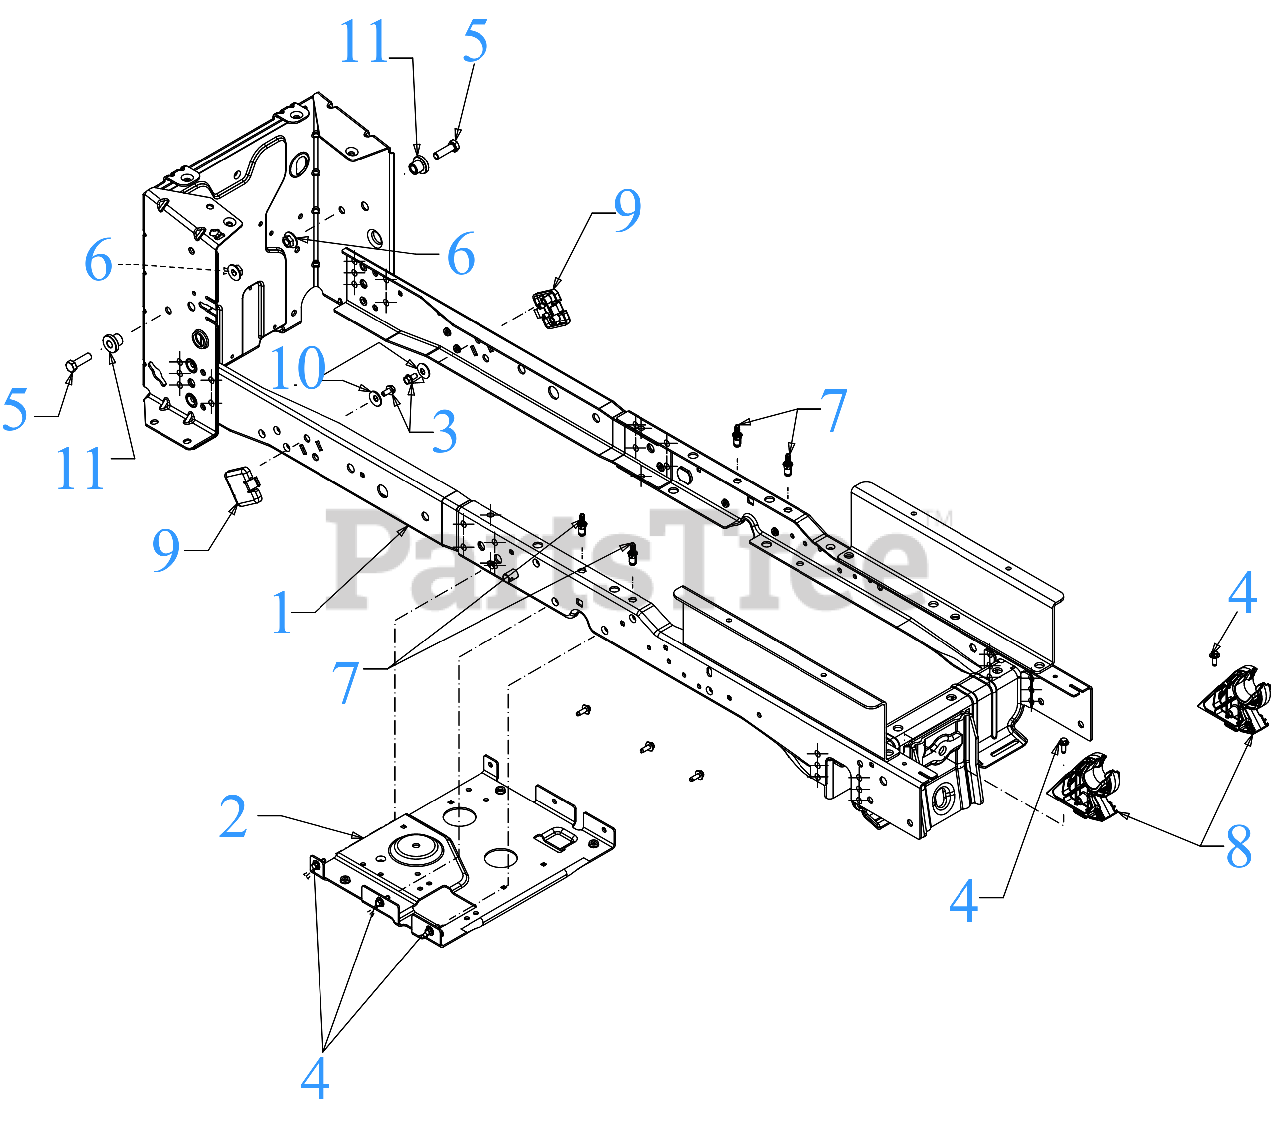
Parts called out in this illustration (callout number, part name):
1	SPLIT FRAME RAIL
2	FRAME BRACE BRACKET (LOWER)
3	HEX SCREW 1/4-15 x .50
4	SCREW M6-1 x .625
5	SCREW 3/8-16 x 1.25 GR5
6	FLANGE LOCK NUT
7	RIVET-HEX STUD 1/4-20 FRM
8	HOOD PIVOT BRACKET
9	LIFT ROD WEAR PAD
10	BELL WASHER .337 X.867 x .057
11	SHOULDER SPACER
